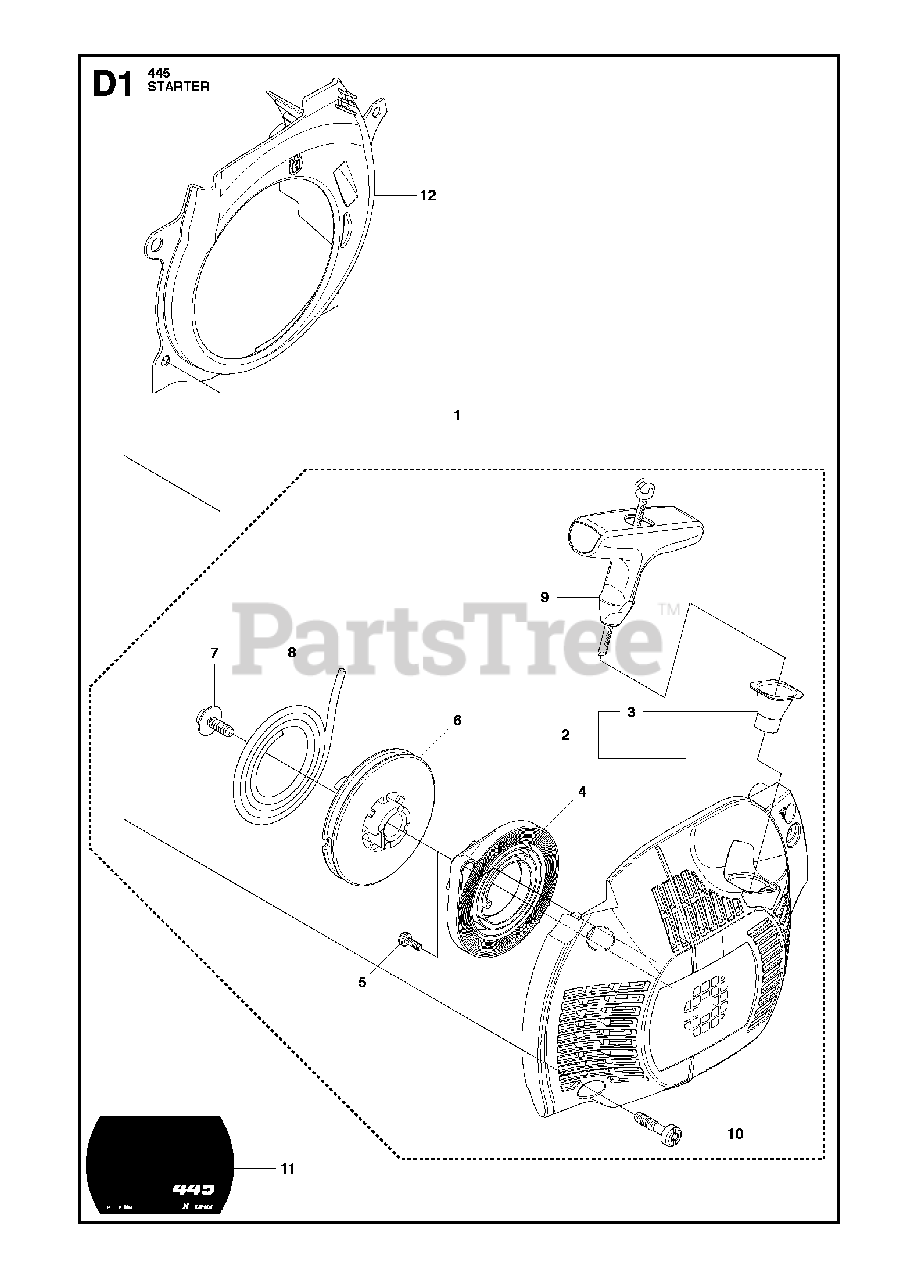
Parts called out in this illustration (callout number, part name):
1	STARTER ASSY
2	STARTER HOUSING
3	SLEEVE
4	SPRING CASSETTE ASSY
5	SCREW
6	PULLEY
7	SCREW
8	STARTER ROPE
9	HANDLE
10	SCREW
12	COOLING AIR CONDUCTOR
